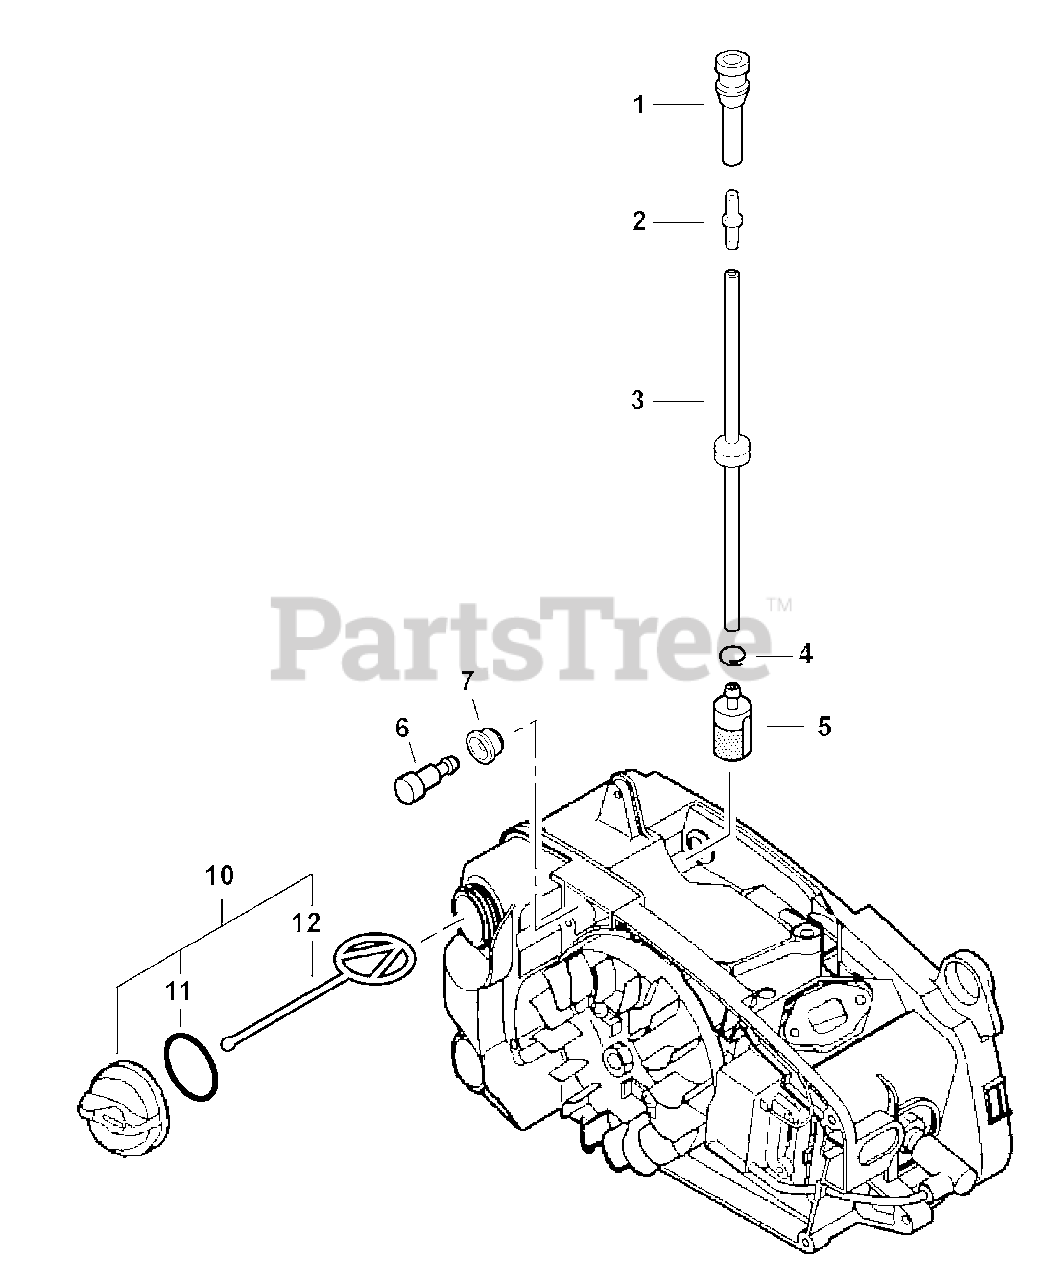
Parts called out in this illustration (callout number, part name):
1	PIPE - FUEL
2	CONNECTOR, PIPE
3	FUEL PIPE ASSY
4	CLIP - 6
5	FILTER, FUEL
6	VENT, FUEL TANK
7	GROMMET
10	CAP ASSY
11	O-RING - 18
12	CONNECTOR, CAP
